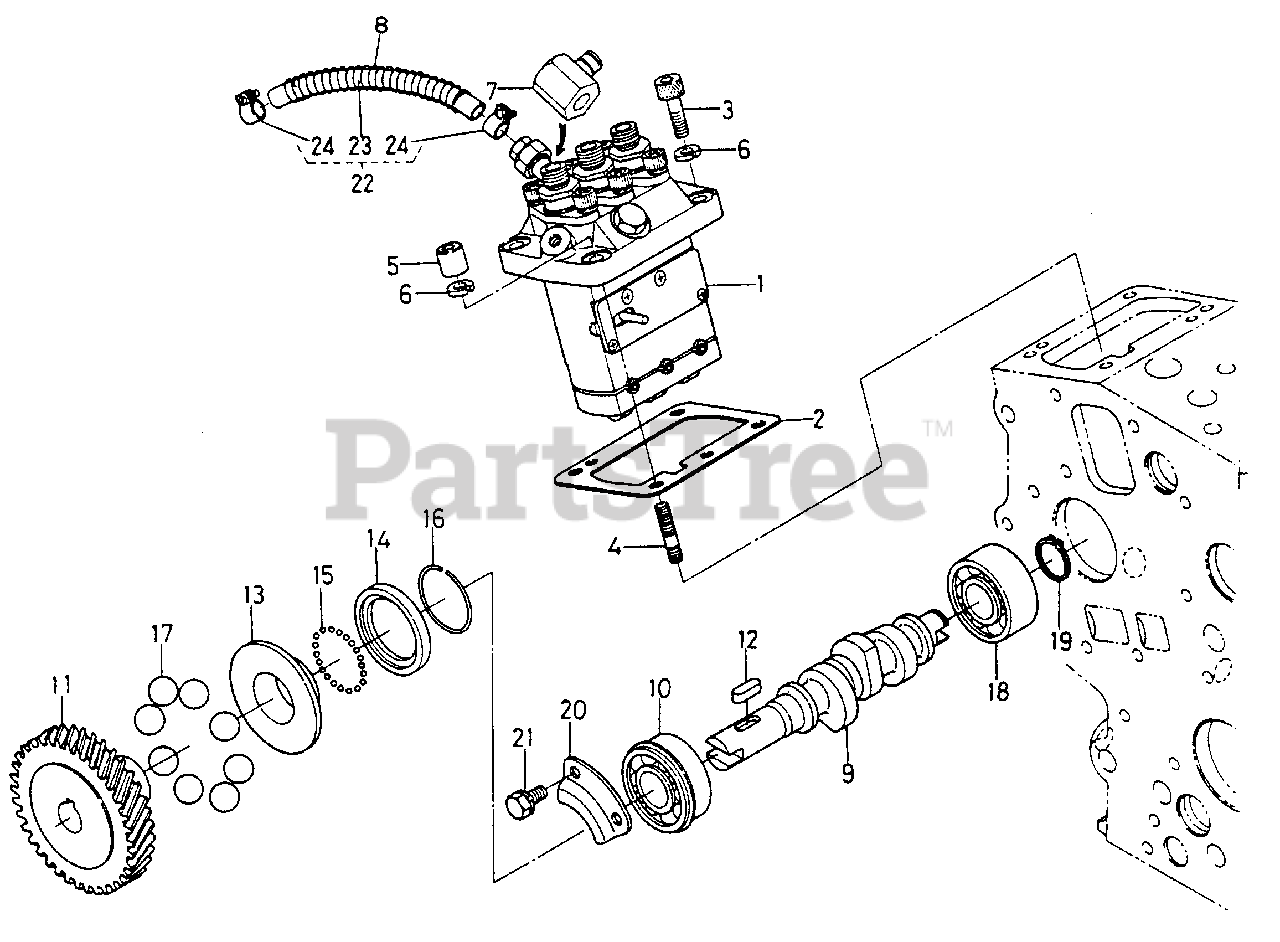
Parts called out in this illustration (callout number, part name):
1	Pump, Injection
2	Shim, Injection Pump
3	Screw, M6 X 20 Pln H/Shd Cap
6	Washer, 6MM Lock
9	Camshaft, Fuel Injection
10	Bearing, Ball
11	Gear, Injection Pump
13	Sleeve, Governor
14	Case, Governor Ball
16	Ring, Governor Sleeve Ret
18	Bearing, Ball
19	Ring, 15.34 MM Ext Ret
20	Stop, Fuel Camshaft
21	Bolt, M6 X 12 Class 8.8
22	Pipe Assy, Fuel
